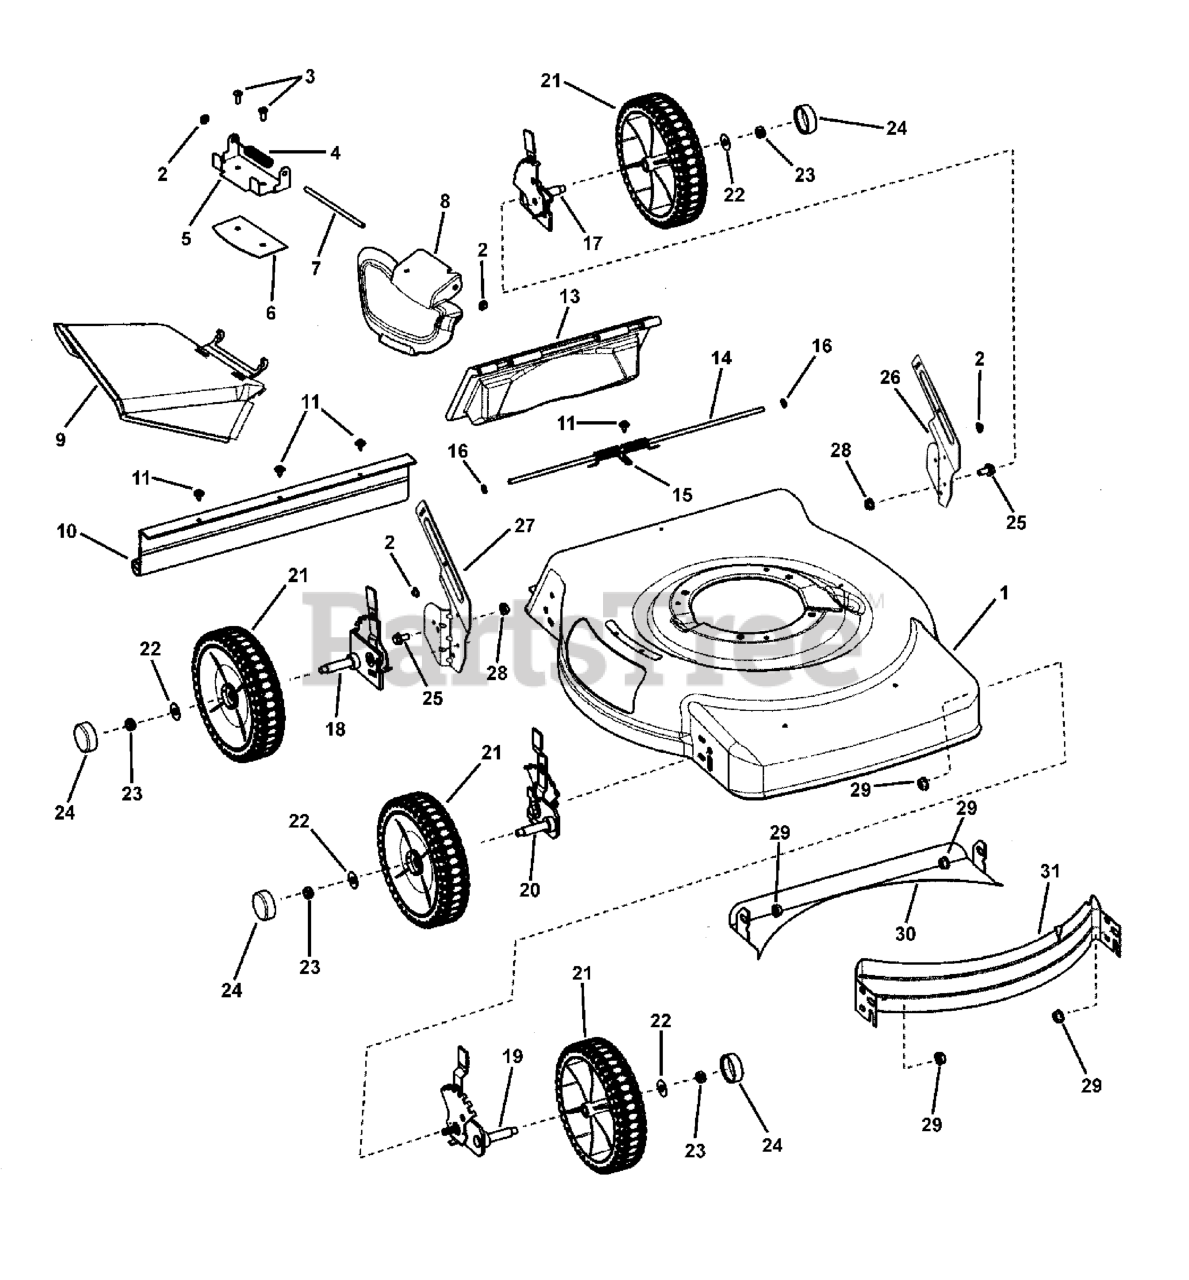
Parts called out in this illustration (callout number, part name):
1	DECK, 22" Walk, Push 3-N-1
2	PUSHNUT, 1/4
3	SCREW, Pan Head, Self Tap, Torx, 1/4-20 x 1/2
4	SPRING, Chute, Torsion
5	BRACKET, Chute
6	PLATE, Mulch
7	ROD, Chute Pivot, 1/4 Dia. x 5-1/2
8	COVER, Mulch
9	SIDE CHUTE
10	GUARD, Rear
11	SCREW, Hex Washer Self Tap, Sems, #10-24 x 1/2
13	DOOR, Rear Discharge
14	ROD, Pivot, Rear Door, 1/4 Dia. x 17-1/2
15	SPRING, Torsion, Rear Door
16	CAP, Retainer
17	ASSEMBLY, Height-of-Cut, Left Rear, 7 Position
18	ASSEMBLY, Height-of-Cut, Right Rear, 7 Position
19	ASSEMBLY, Height-of-Cut, Left Front, 7 Position
20	ASSEMBLY, Height-of-Cut, Right Front, 7 Position
21	ASSEMBLY, Wheel, 8"x 2" Idle, NB Murray Tread, Gray
22	WASHER, Flat, 3/8 ID, 1 OD
23	NUT, Hex Center Lock, 3/8-16
25	BOLT, Hex Flange Lock, 5/16-18 x 5/8
26	BRACKET, Lower Handle, Right
27	BRACKET, Lower Handle, Left
28	NUT, Flange Lock, 5/16-18
29	NUT, Hex Flange Lock, 3/8-16 GR 5
30	BAFFLE, Rear
31	BAFFLE, Front
